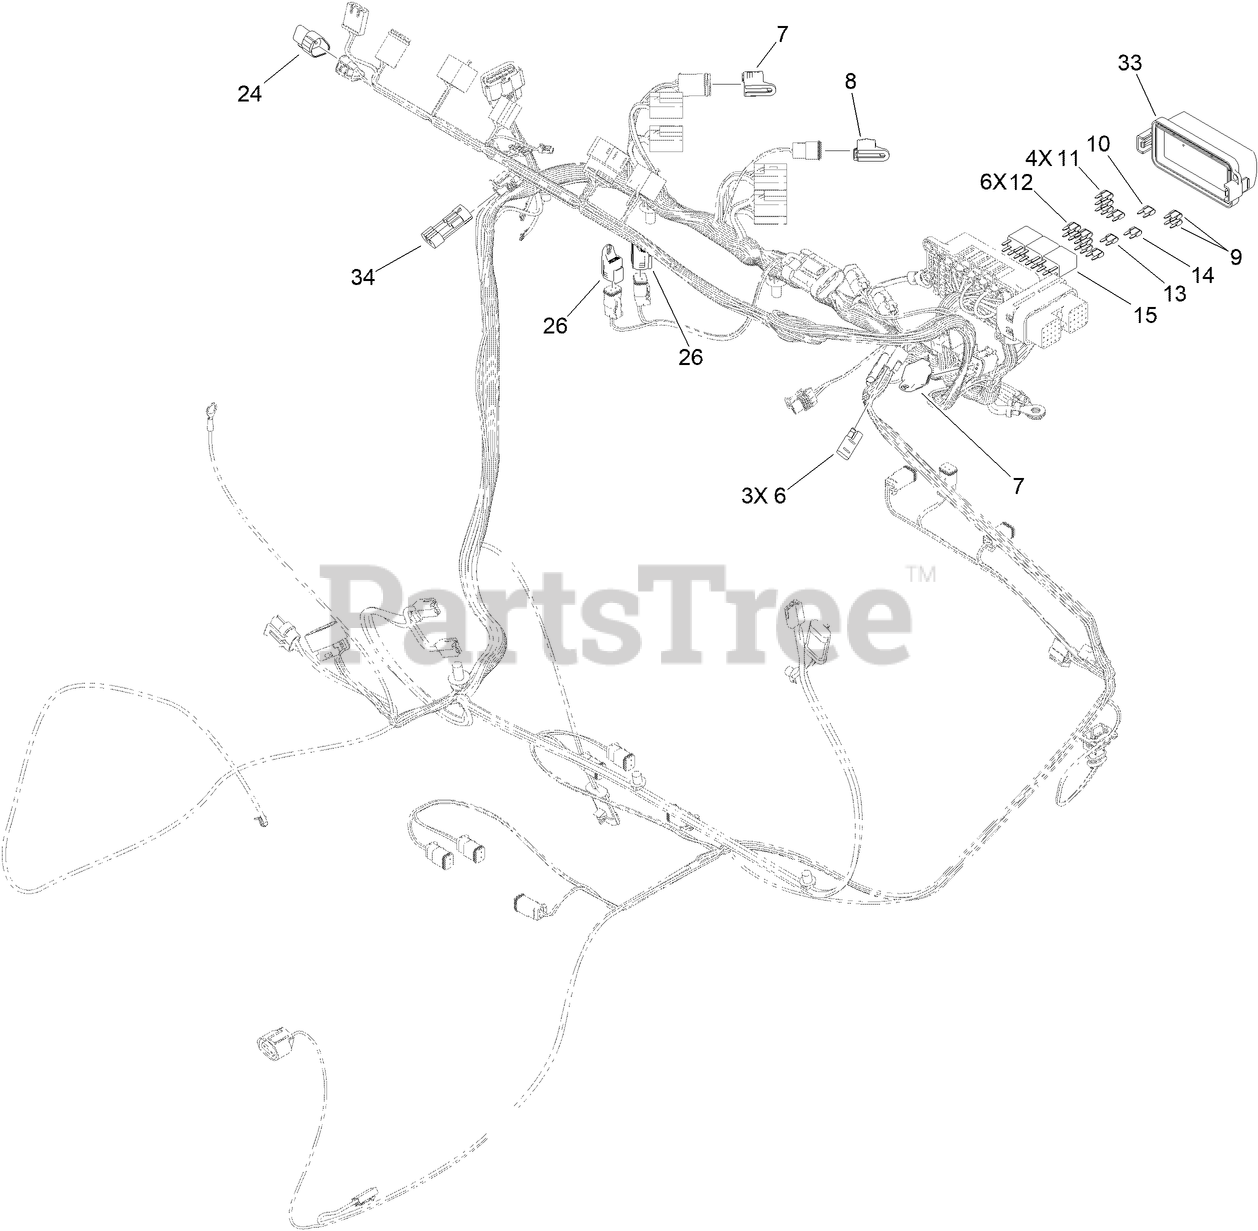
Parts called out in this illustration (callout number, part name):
6	CAP-PLUG
7	CAP-PLUG, 6 WAY
8	CAP-PLUG, 3 WAY
9	FUSE-MINI BLADE, 2 AMP
10	FUSE-MINI BLADE, 5 AMP
11	FUSE-MINI BLADE, 7.5 AMP
12	FUSE-MINI BLADE, 10 AMP
13	FUSE-MINI BLADE, 20 AMP
14	FUSE-MINI BLADE, 25 AMP
15	RELAY-280 ISO
24	RESISTOR-120 OHM
26	CAP-DUST, 2 WAY
33	COVER-LITTELFUSE, PDM 60F
34	CONNECTOR
